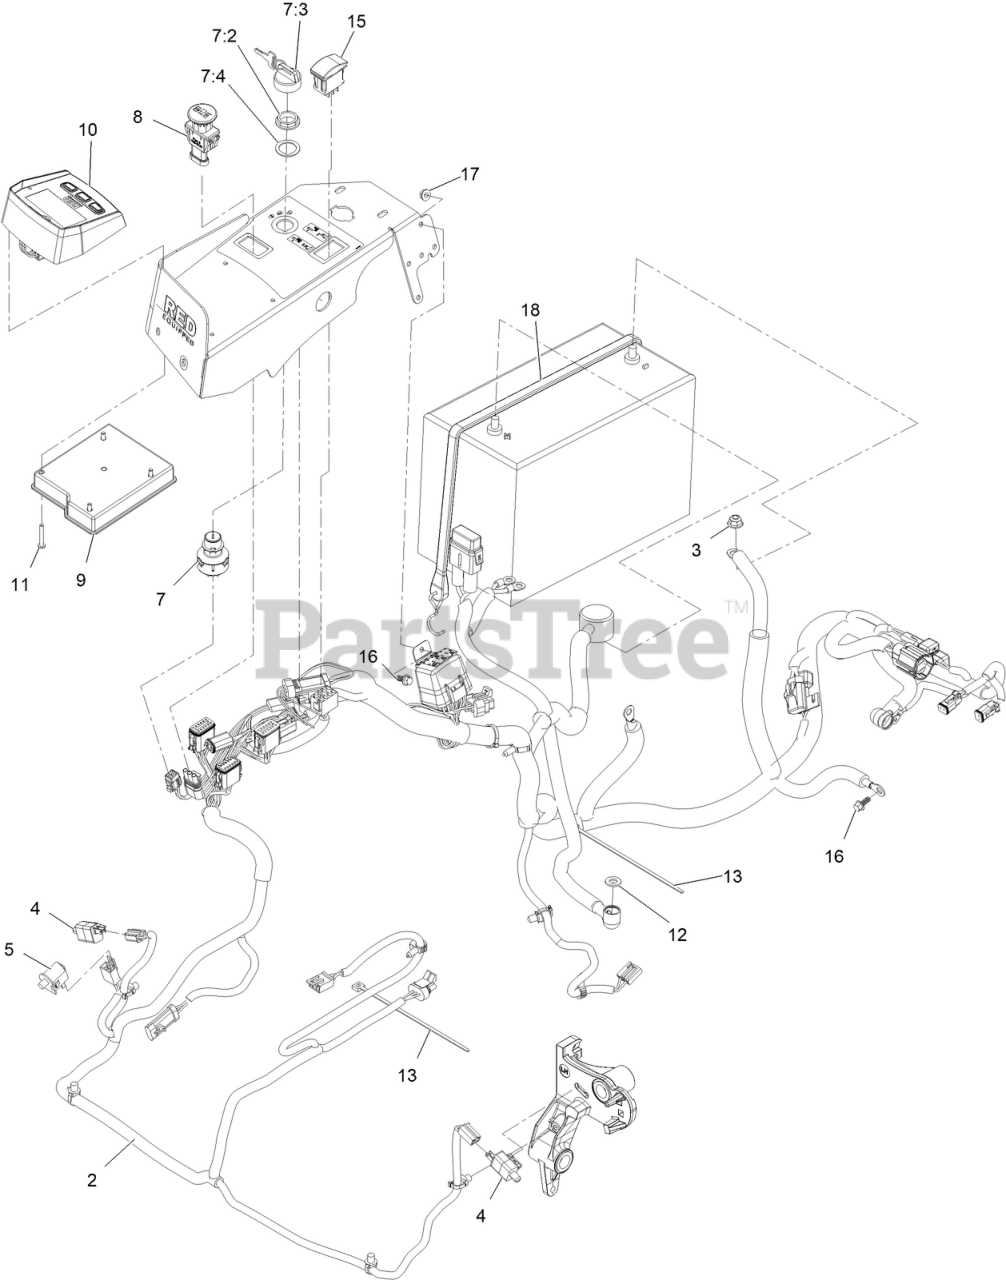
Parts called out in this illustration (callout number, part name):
2	Harness-Wire
3	NUT-HF, NI
5	SWITCH-BAIL
7	IGNITION SWITCH ASM
7:2	NUT-MOUNTING
7:3	IGNITION KEY SET
7:4	WASHER-BACKUP
8	SWITCH-PTO, SEALED
9	Module-Mcu
10	MODULE, LDU
11	SCREW-PPH
12	WASHER-FLAT
13	TIE-CABLE
16	SCREW-HHF
